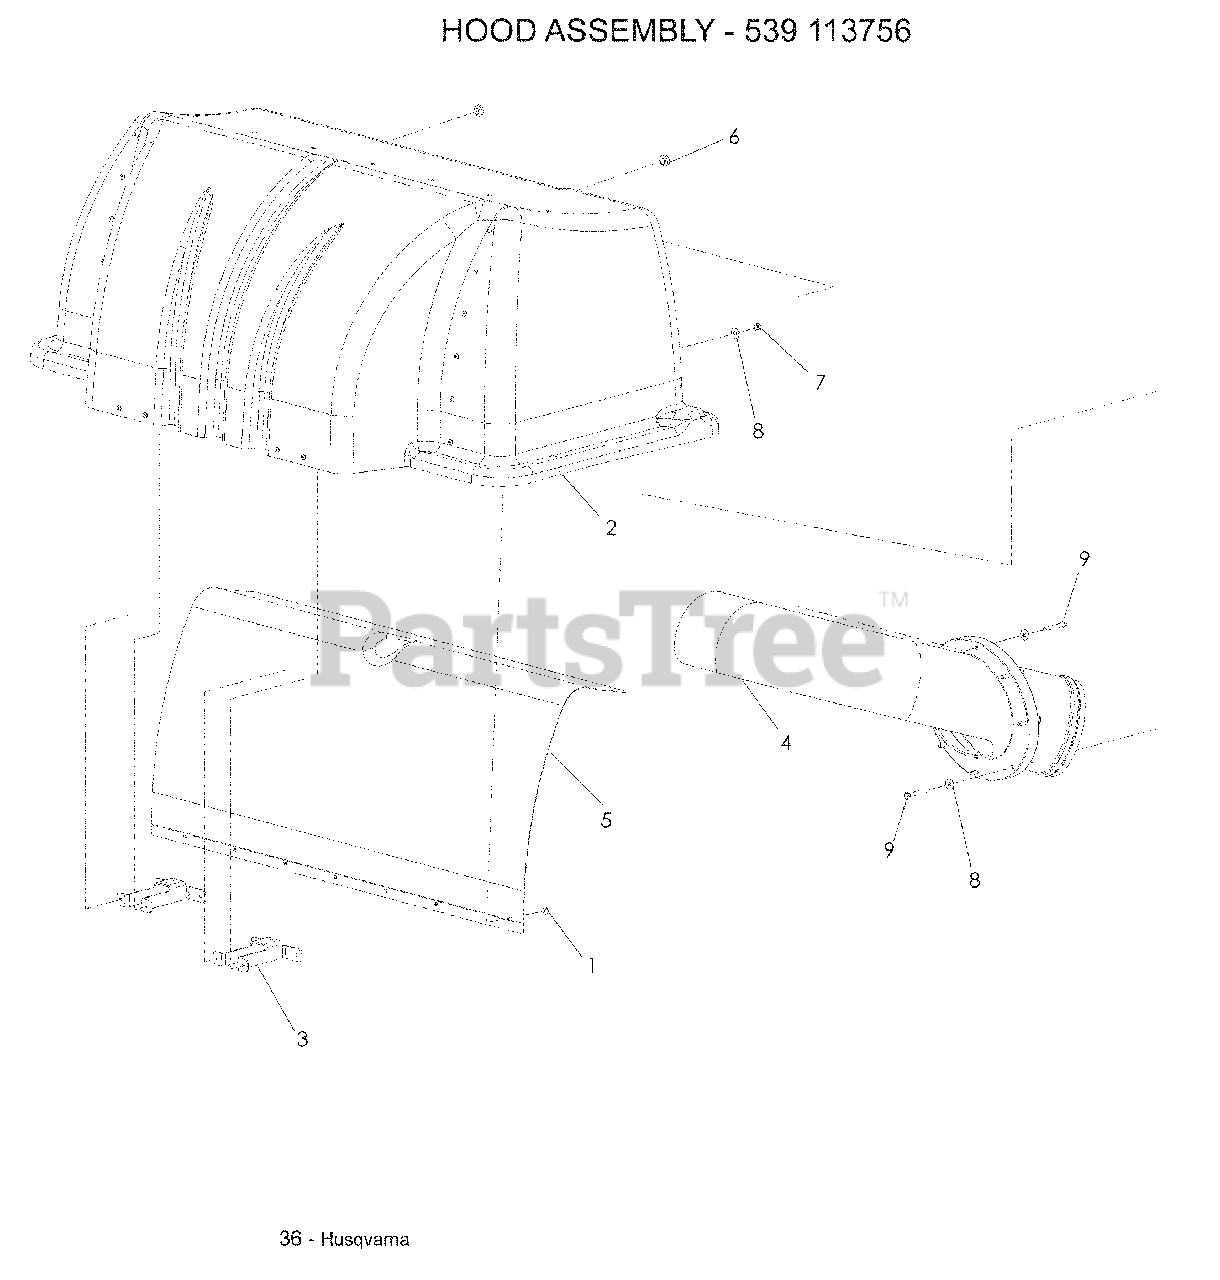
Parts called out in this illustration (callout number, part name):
1	WASHER #10
3	SUPPORT, DRAW LATCH
4	INLET TUBE
5	MESH, POLY DIAMOND
7	NUT ¼-20 HEX NYLOC
9	HCS ¼-20 x 1¾
